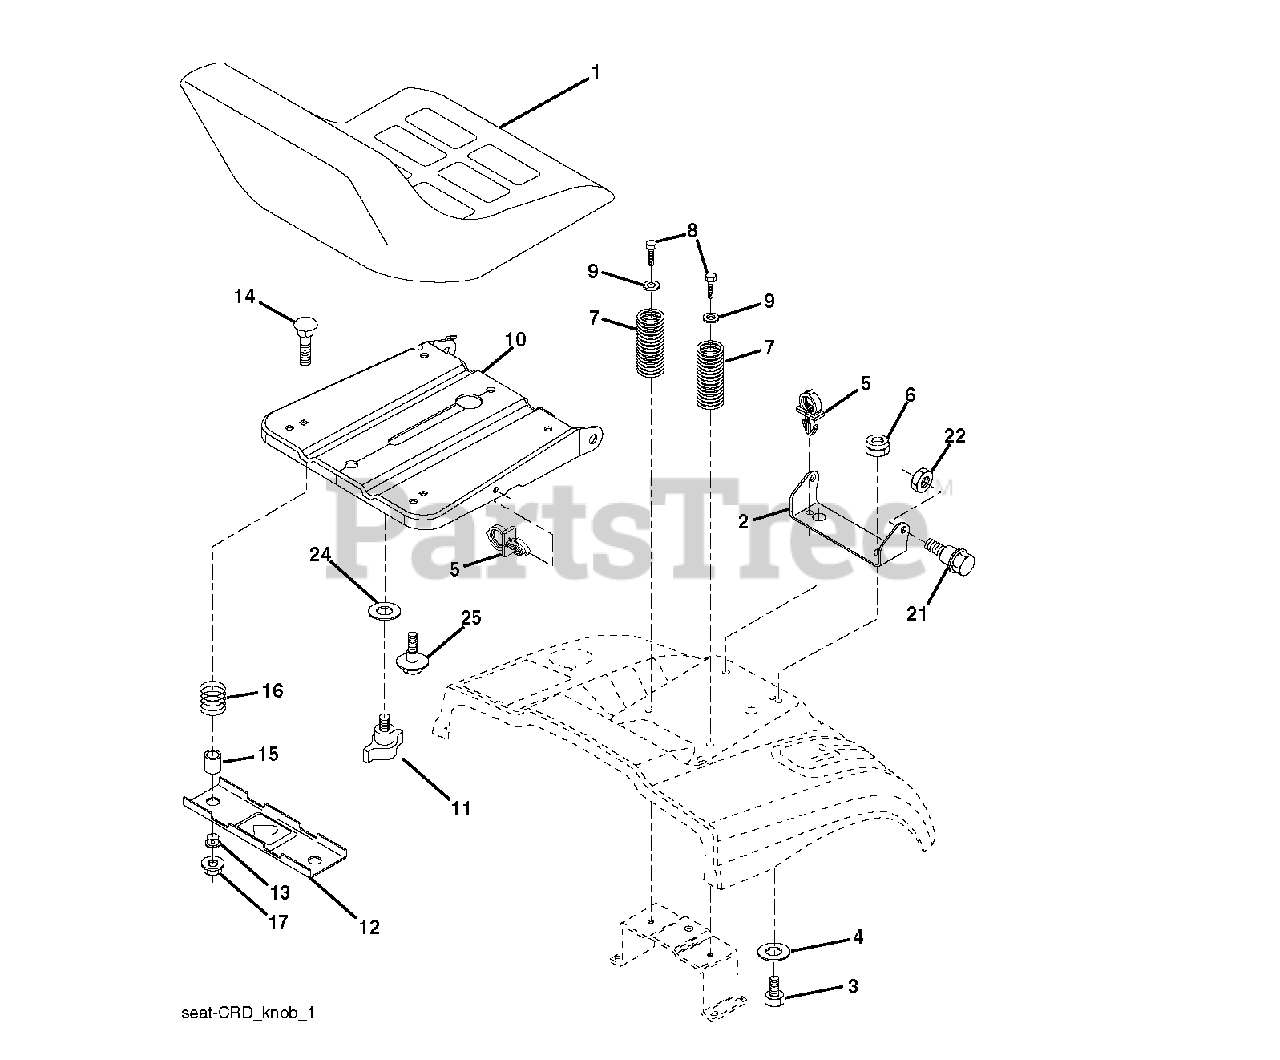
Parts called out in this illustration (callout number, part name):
2	SEAT PIVOT BRKT
4	WASHER PM
5	PUSH CLIP
6	NUT
7	SPRING COMPRESSION
8	SCREW 3/8-16X1
9	WASHER
10	PAN.ASM.SEAT.1SLOT
11	KNOB.SEAT.ADJ.WINGNUT
12	BRKT.MNTNG.SWITCH.SEAT
14	BOLT.ROUND.HEAD.SQUARE.NECK
15	SPACER SPLIT 28X.96
17	NUT T
21	BOLT.SHOULDER.5/16-18
22	NUT.71038.31-18.HEX.NYLOCK
25	BOLT,SHOULD
